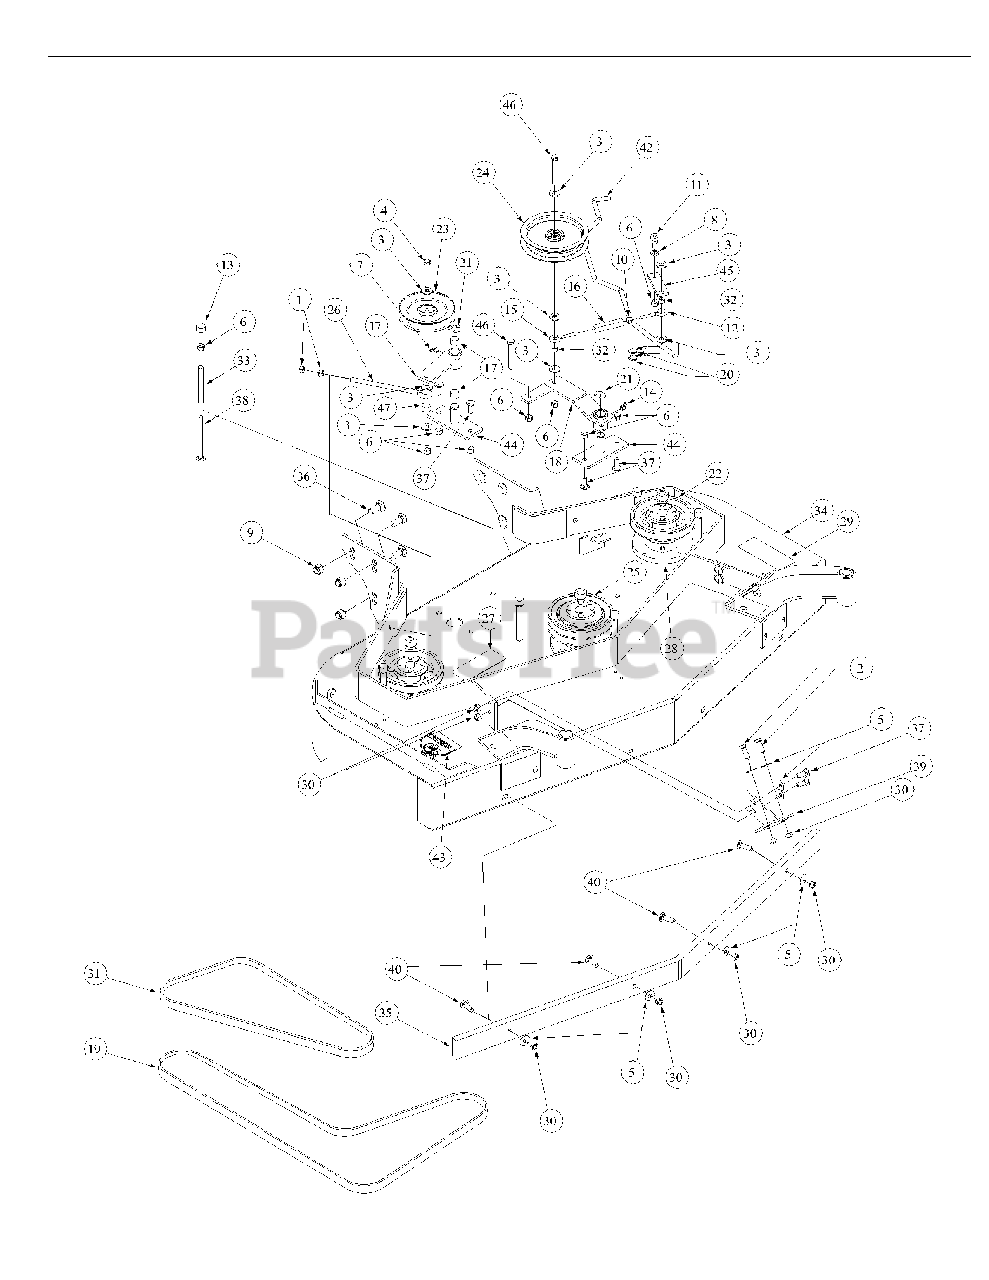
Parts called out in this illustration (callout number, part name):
1	Hex Nut, 3/8-16
2	Hex Cap Screw, 3/8-16, 1
3	Flat Washer, 3/8 Zinc
4	Hex Cap Screw, 3/8-16, 1
5	Flat Washer, 3/8 Zinc
6	Lock Nut, Nylon Insert, 3/8-16
7	Grease Fitting, 1/4-28, 90°.
8	Shim Washer
9	Lock Nut, Nylon Insert, 1/2-
10	Hex Nut, 5/16-18
11	Shoulder Bolt
12	Eye Bolt, Right Hand
13	Vinyl Cap
14	Grease Fitting, 1/4-28, 45°.
15	Eye Bolt, Left Hand
16	Turnbuckle
17	Idler Arm "B"
18	Idler Arm "A"
19	Drive Belt
20	Hair Pin, 3/8"-1/2"
22	Deck Pulley
23	Idler Pulley
24	Idler Deck Take-up
25	Double Pulley
26	Rod Belt Tensioner
27	Decal Warning Shield Missing
28	Spindle Backing Plate
29	Decal Rotating Blade
30	Lock Nut, Metal, 3/8-16
31	Drive Belt
32	Sleve Turnbuckle
33	Spacer Belt Guide
34	Deck Weldment Mower
36	Carriage Bolt, 1/2-13 x 1-1/4
37	Carriage Bolt, 3/8-16 x 2
38	Carriage Bolt, 3/8-16 x 4-1/2
39	Caster Support Assembly
40	Carriage Screw, 3/8-16 x 1-1/4
42	Rod Clutch Link
43	Decal, Danger Hands and Feet
44	Idler Base
46	Hex Cap Screw, 3/8-16, 2.75
47	Sleeve Tensioner
